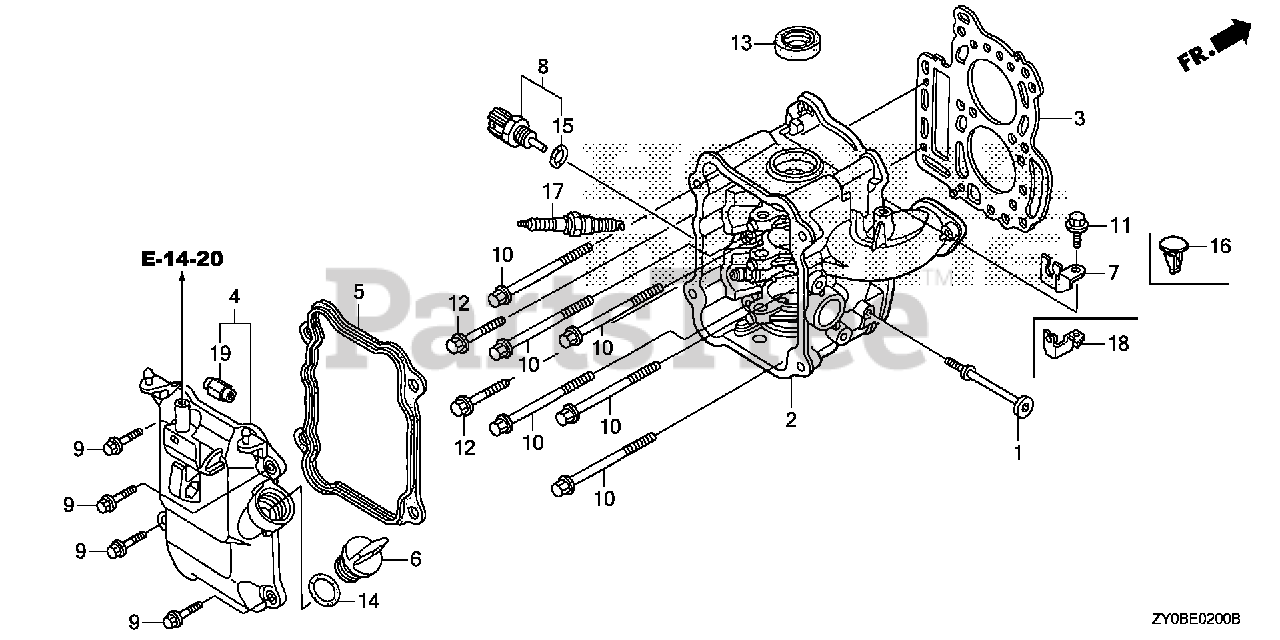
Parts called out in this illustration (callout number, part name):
1	STOPPER, ENGINE SIDE
2	CYLINDER HEAD (000) *NH8* (DARK GRAY)
3	GASKET, CYLINDER HEAD
4	COVER, HEAD
5	GASKET, HEAD COVER
6	CAP, OIL
7	HOLDER, CABLE
8	SENSOR ASSY., WATER TEMPERATURE
9	BOLT, FLANGE (6X22)
10	BOLT, FLANGE (8X83)
11	BOLT, FLANGE (6X14) (CT200)
12	BOLT, FLANGE (8X40)
13	OIL SEAL (20X32X6)
14	O-RING (26X2.7)
15	O-RING (9.5X1.5) (HONDA KIKAKI)
17	SPARK PLUG (CR5EH-9) (NGK)
17	SPARK PLUG (U16FER9) (DENSO)
18	HOLDER, CABLE
19	NUT, INSERT
